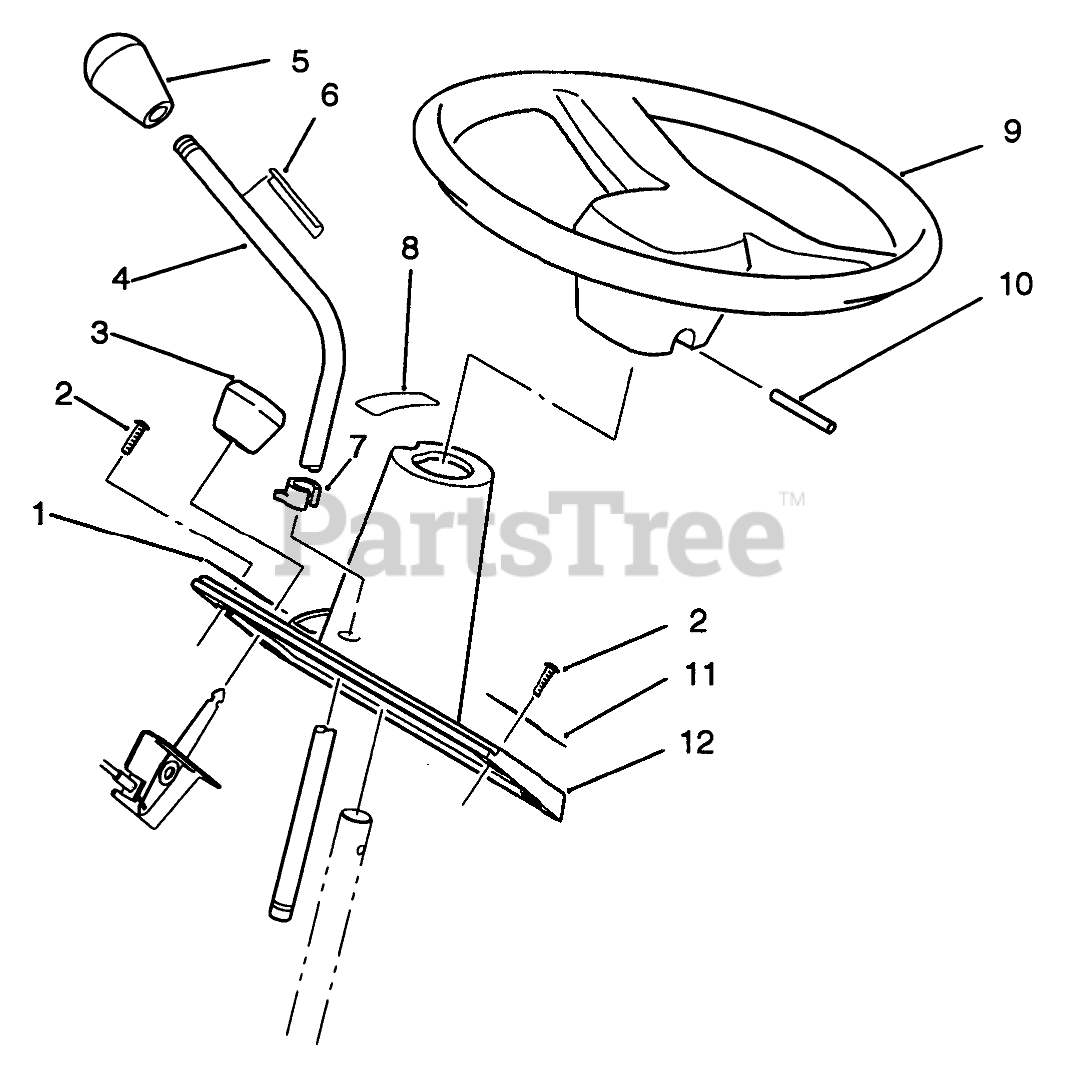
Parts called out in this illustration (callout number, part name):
1	Decal-Throttle
2	SCREW
3	KNOB-THROTTLE
4	ROD-SHIFT LEVER
6	DECAL-MOTION CONTROL
7	POINTER
8	DECAL-HYDRO MOTION
9	Steering Wheel
10	PIN-ROLL
11	Decal-Height of Cut
12	CONSOLE
